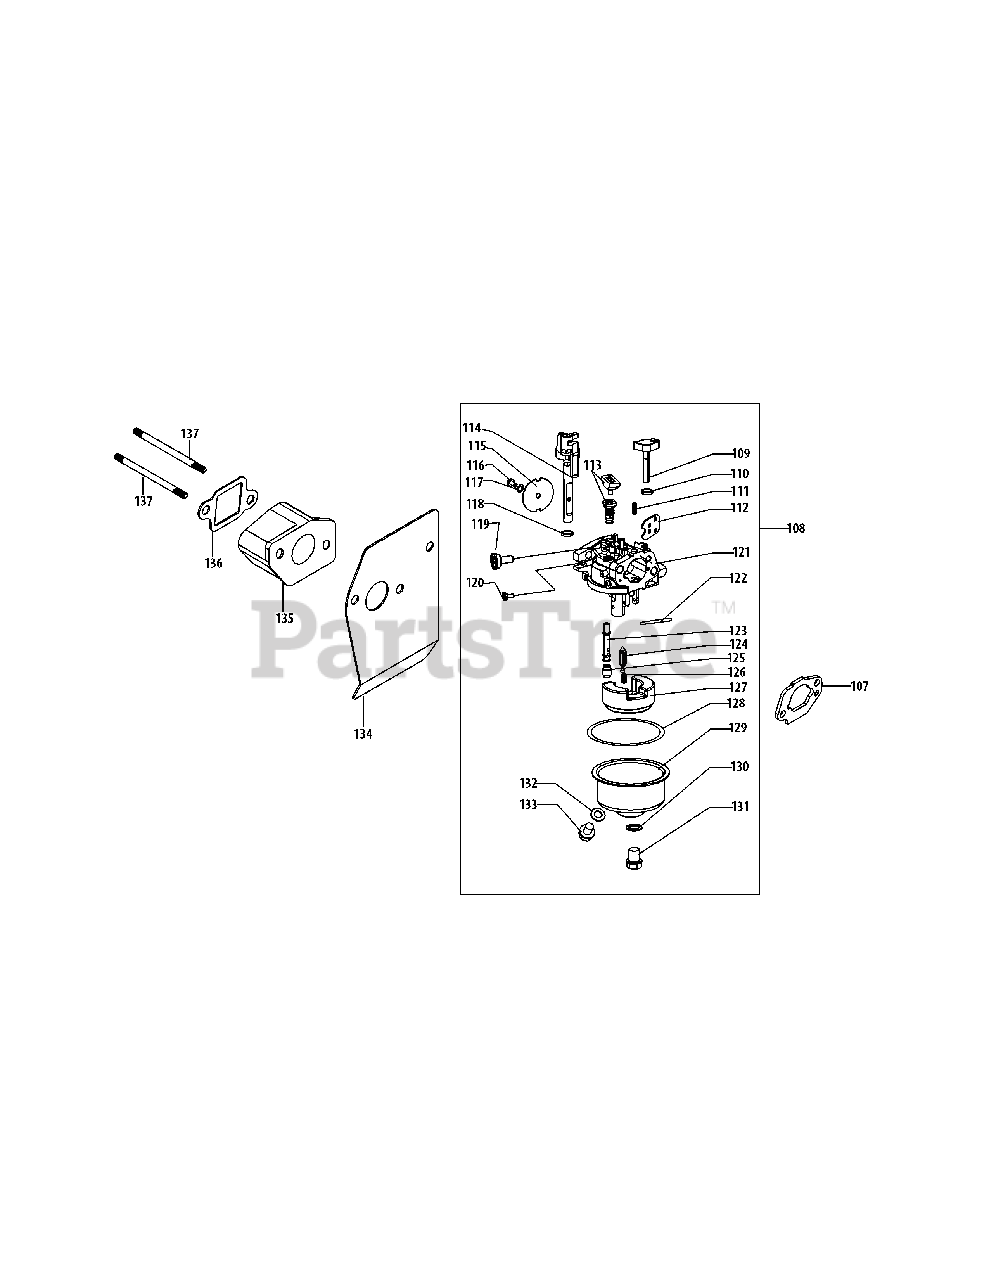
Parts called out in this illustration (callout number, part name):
107	Carburetor Gasket Plate
108	Carburetor Assembly
109	Choke Shaft
110	Fiber O-Ring
111	Choke Plate
112	Choke Return Spring
113	Idle Jet Assembly
114	Throttle Shaft
115	Throttle Plate
116	Lock Washer
117	Screw M3×6
118	Fiber O-Ring
119	Idle Speed Adjusting Screw
120	Idle Mixture Screw
121	Carburetor Body
122	Float Pin
123	Emulsion Tube
124	Needle Valve
125	Main Jet
126	Needle Valve Spring
127	Float
128	Fuel Bowl O-Ring
129	Fuel Bowl
130	Fuel Bowl Gasket
131	Fuel Bowl Mounting Bolt
132	Fuel Drain Plug Gasket
133	Fuel Drain Plug
134	Carburetor Gasket
135	Carburetor Insulator
136	Carburetor Insulator Gasket
137	Carb Stud M6×113
